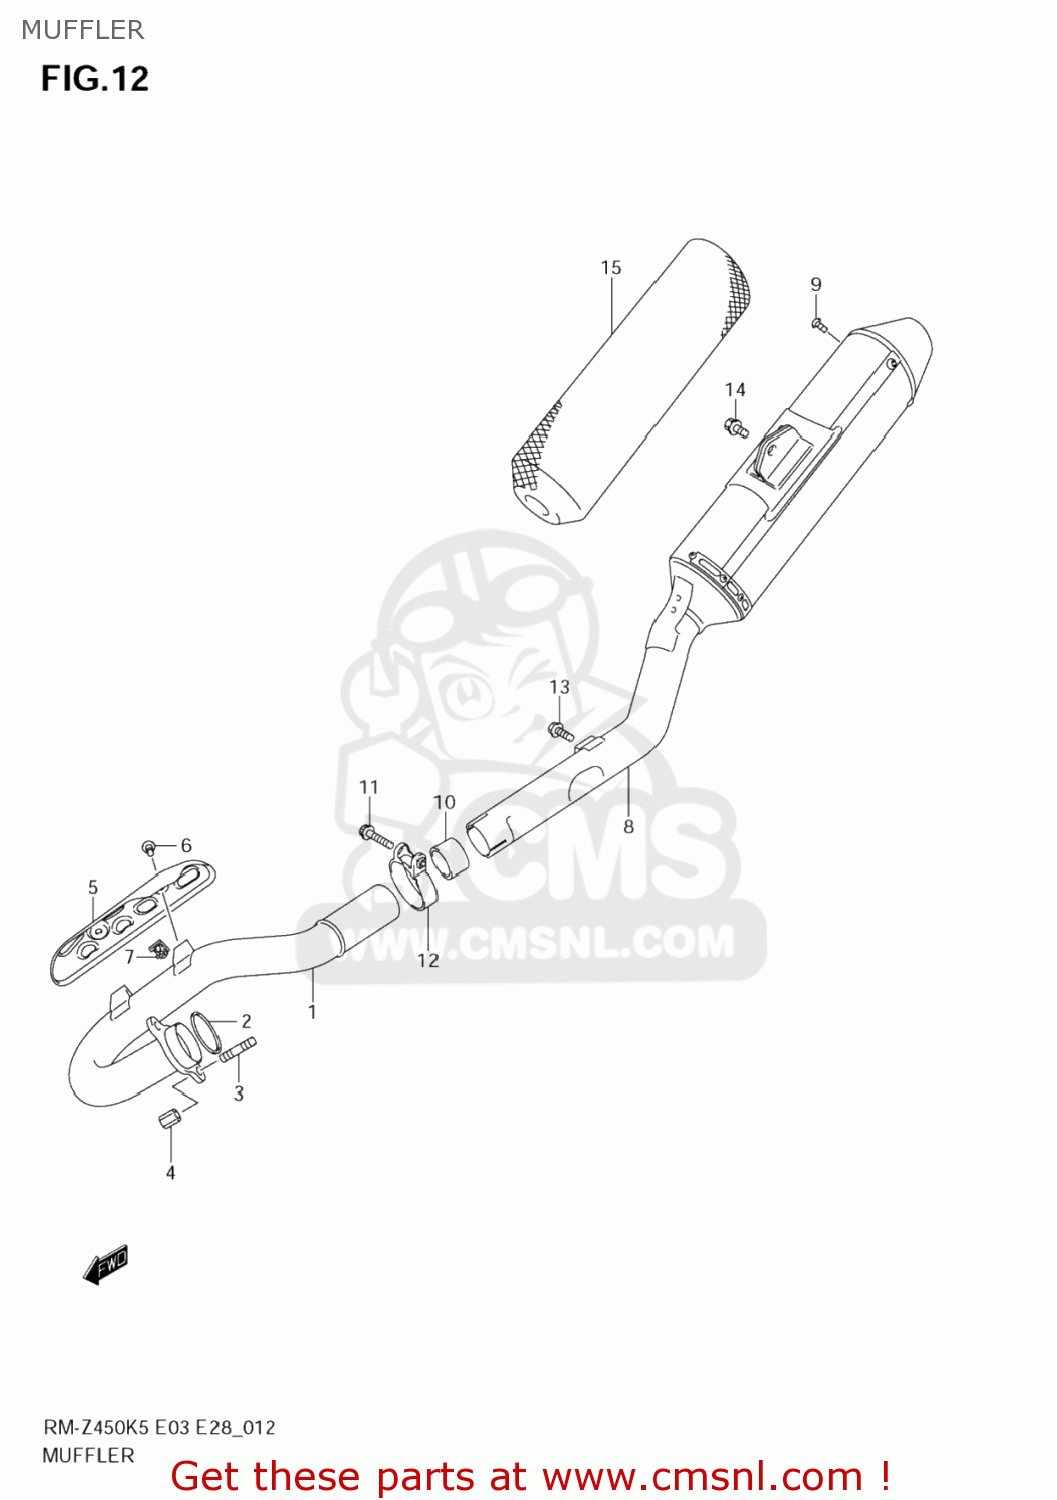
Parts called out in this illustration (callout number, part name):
1	PIPE,EXHAUST
2	GASKET,EXHAUST PIPE (NAS)
3	BOLT
4	NUT
5	COVER,EXHAUST
6	SCREW(6X10)
7	NUT
8	BODY,MUFFLER
9	SCREW(5X13)
10	CONNECTOR,MUFFLER JOINT
11	BOLT
12	CLAMP,CONNECTOR
13	BOLT(8X16)
14	BOLT
15	SILENCER,MUFFLER
